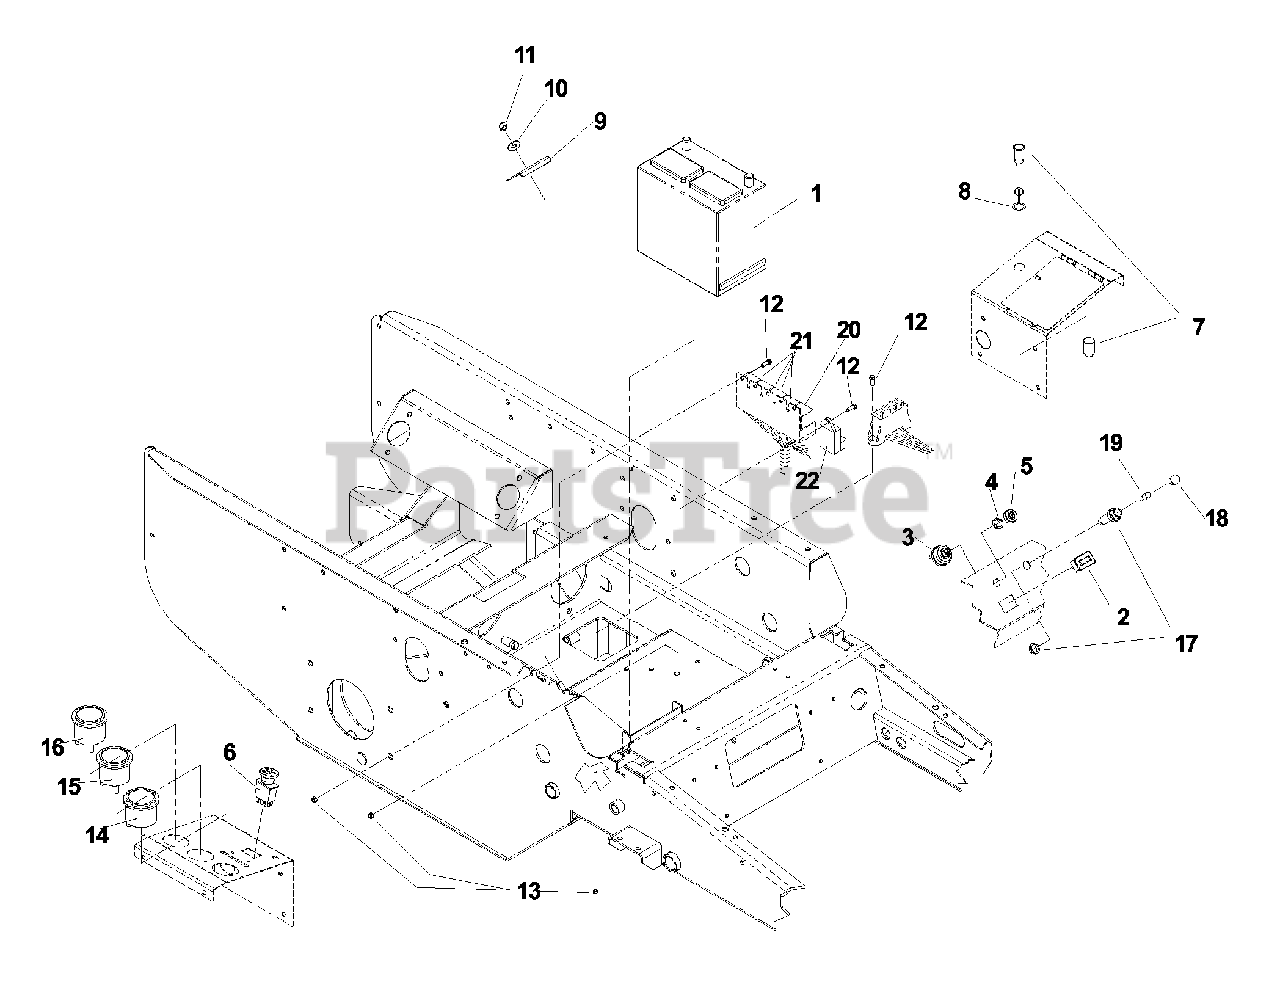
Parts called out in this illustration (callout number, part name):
2	Hourmeter, LCD w/flash alert
3	Switch, ignition
4	Nut, ignition switch
5	Cap, ignition switch nut
6	Switch, clutch
7	Power source housing
8	Power source cap
10	Washer, 5/16
11	Nut, 5/16-18
12	Bolt, , #10-24 x 3/4
13	Nut, #10-24, nyloc
14	Gauge, temperature
15	Gauge, amperes
16	Gauge, oil pressure
17	Lamp socket
20	Relay, Glow Plug
22	Timer/glow plug
